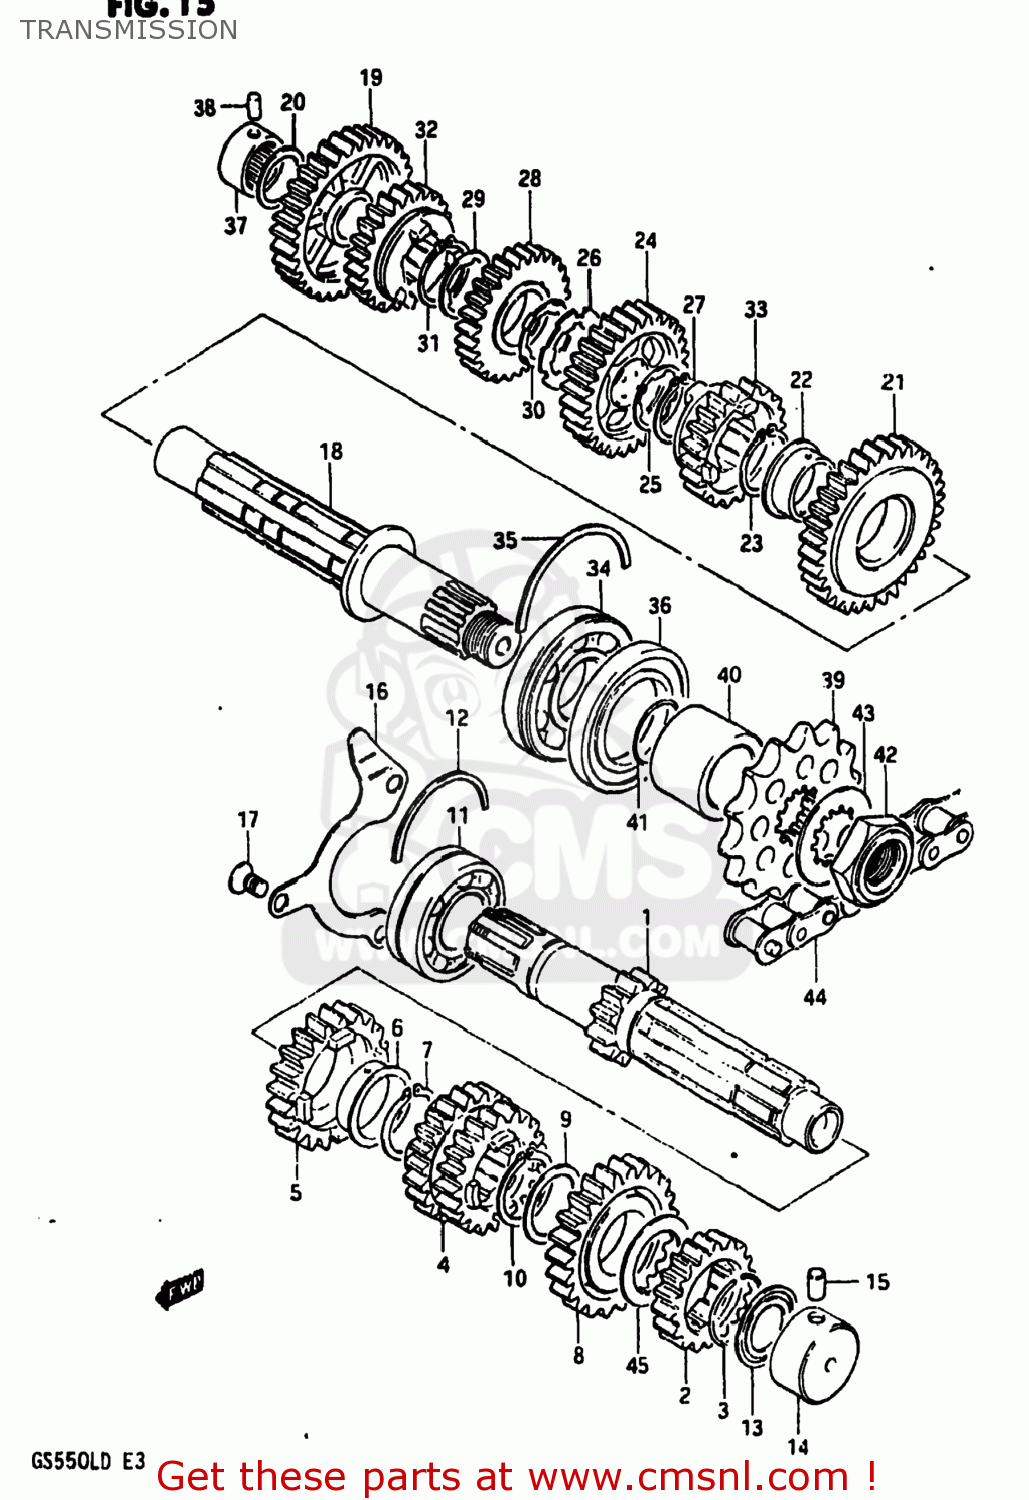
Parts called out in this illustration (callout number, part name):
1	SHAFT,COUNTER
2	GEAR,SECOND DRIVE
3	RING,SNAP
4	GEAR,THIRD/FOURTH DRIVE
5	GEAR,FIFTH DRIVE
6	BUSHING
7	RING,SNAP
8	GEAR,SIXTH DRIVE
9	WASHER,LOCK
10	RING,SNAP
11	BEARING(25X52X19.6)
12	C RING
13	SEAL,OIL(20X31.2X2.7)
14	BEARING(20X34X17.5)
15	PIN
16	PLATE,COUNTERSHAFT BEARING
17	SCREW
18	SHAFT,DRIVE
19	GEAR,FIRST DRIVEN
20	WASHER
21	GEAR,SECOND DRIVEN
22	BUSHING
23	RING,SNAP
24	GEAR,THIRD DRIVEN
25	WASHER,LOCK
26	WASHER,LOCK
27	RING,SNAP
28	GEAR,FOURTH DRIVEN
29	WASHER,LOCK
30	WASHER
31	RING,SNAP
32	GEAR,FIFTH DRIVEN
33	GEAR,SIXTH DRIVEN
34	BEARING(25X62X17)
35	C-RING
36	SEAL,OIL(33X62X7)
37	BEARING(20X34X20)
38	PIN
39	SPROCKET,ENGINE
40	SPACER
41	O RING(D:1,ID:24.5)
42	NUT
43	WASHER
44	CHAIN ASSEMBLY,DRIVE
45	SHIM
